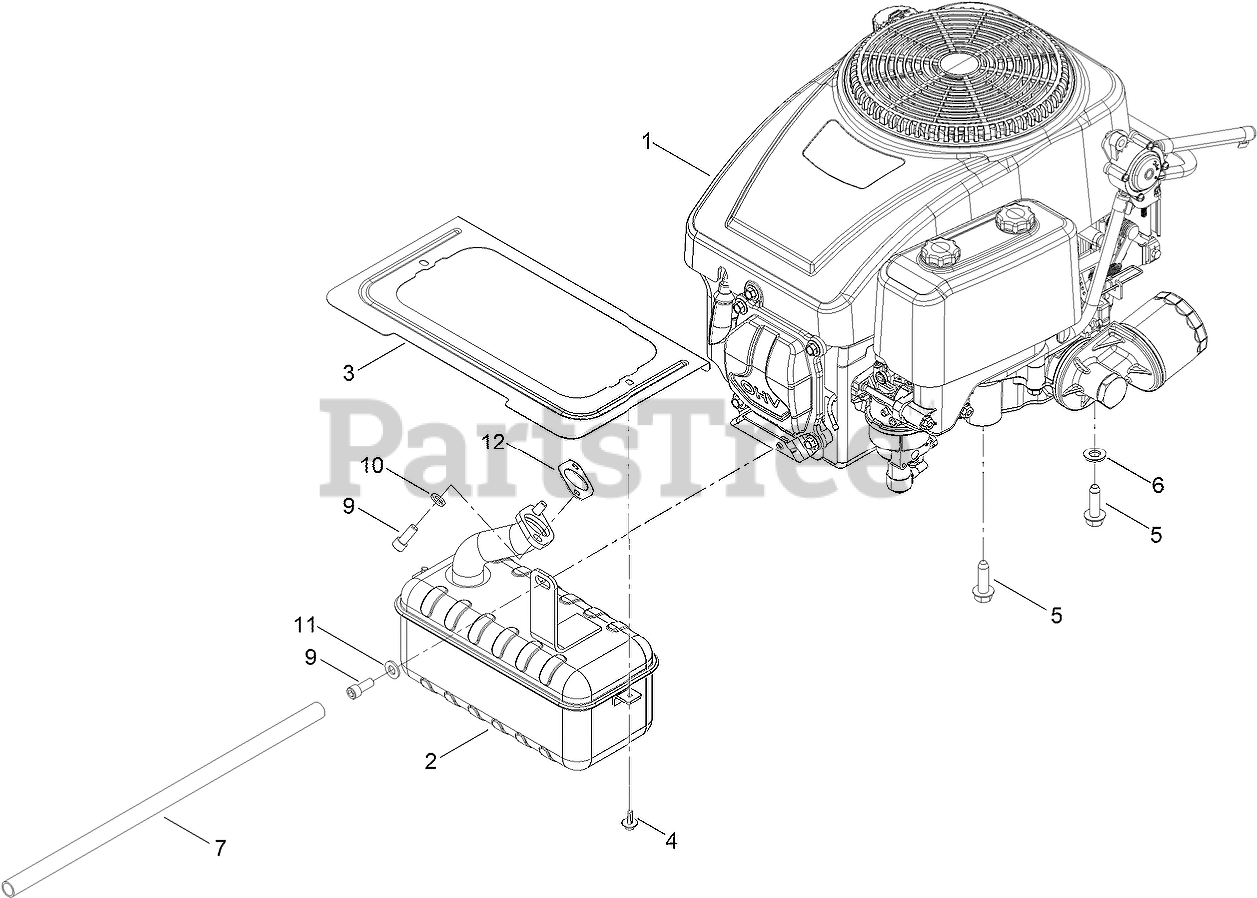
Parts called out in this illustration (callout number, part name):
2	MUFFLER
3	SHIELD-HEAT
4	SCREW-HHFTF
5	SCREW-THD
6	WASHER-FLAT
7	TUBE-DRAIN, OIL
9	SCREW-HSH
10	WASHER-LOCK
11	WASHER-PLAIN
12	GASKET-EXHAUST
